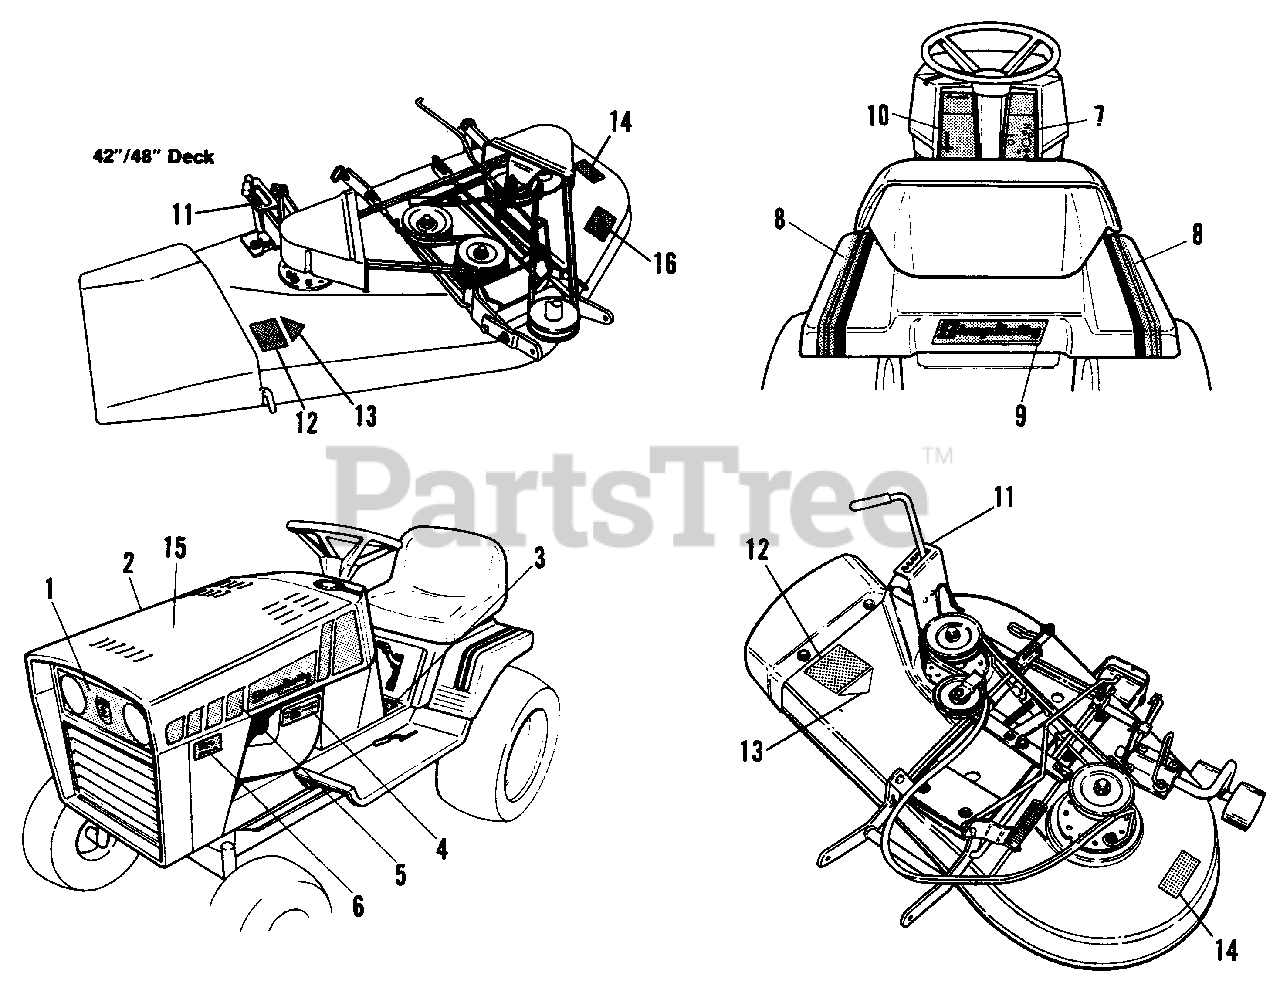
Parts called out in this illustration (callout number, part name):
1	DECAL, Grille
2	DECAL, Hood, R.H.
3	DECAL, Shift
4	DECAL, Engine (5216 Only)
4	DECAL, Engine (5212.5 only)
5	DECAL, Hood, L.H.
6	DECAL, 5216 Hydro
6	DECAL, 5212.5
7	DECAL, Dash, R.H.
8	DECAL, Seat Deck
9	DECAL, Simplicity
10	DECAL, Dash, L.H.
11	DECAL, Mower Height
12	DECAL, Danger
13	DECAL, OPEI
14	DECAL, Danger
15	DECAL, Drive Belts (Inside Hood)
16	DECAL, Caution
